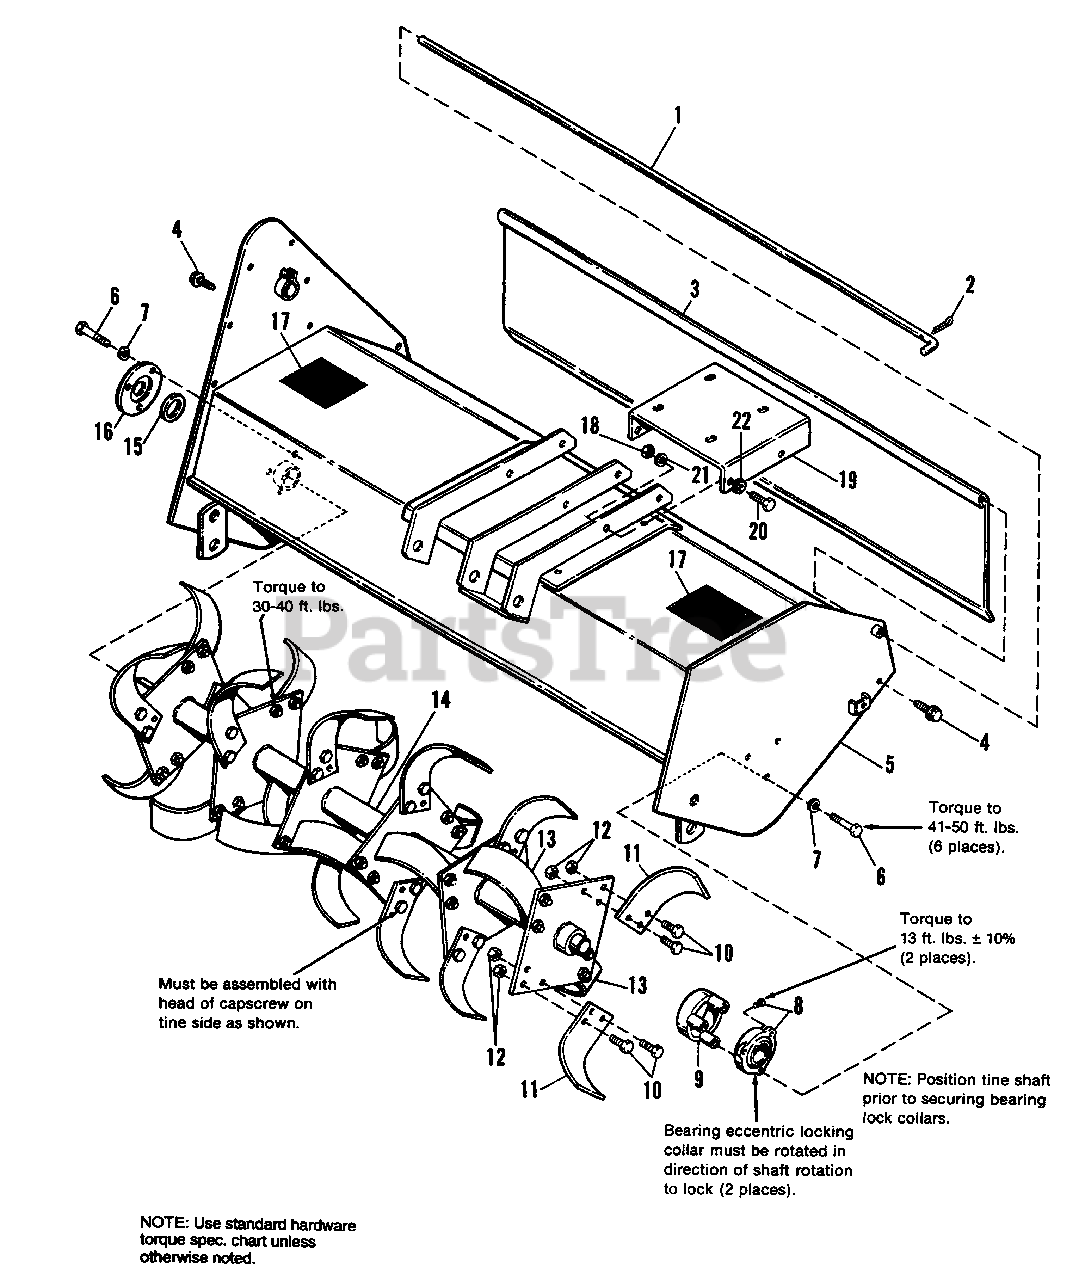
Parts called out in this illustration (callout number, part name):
1	ROD, Deflector
2	PIN, Cotter, 3/32 x 1
4	SCREW, Thd. Form., Taptite, 3/8-16 x 1-1/4
5	HOUSING ASSY.
6	CAPSCREW, Hex Hd., 3/8-16 x 1-1/4
7	LOCKWASHER, 3/8
8	FLANGE, Bearing
9	GUARD ASSY., Trash
10	CAPSCREW, Hex Hd., 3/8-16 x 1
11	TINE, LH.
12	LOCKNUT, Hex, 3/8-16
13	TINE, R.H.
14	Sk AFT ASSY., Tine
16	RETAINER, Seal
17	DECAL, Danger
18	NUT, 3/8-16
19	SUPPORT, Gear Box
20	CAPSCREW, 3/8-16 x 3/4
21	LOCKWASHER, 3/8
22	WASHER, 13/32
